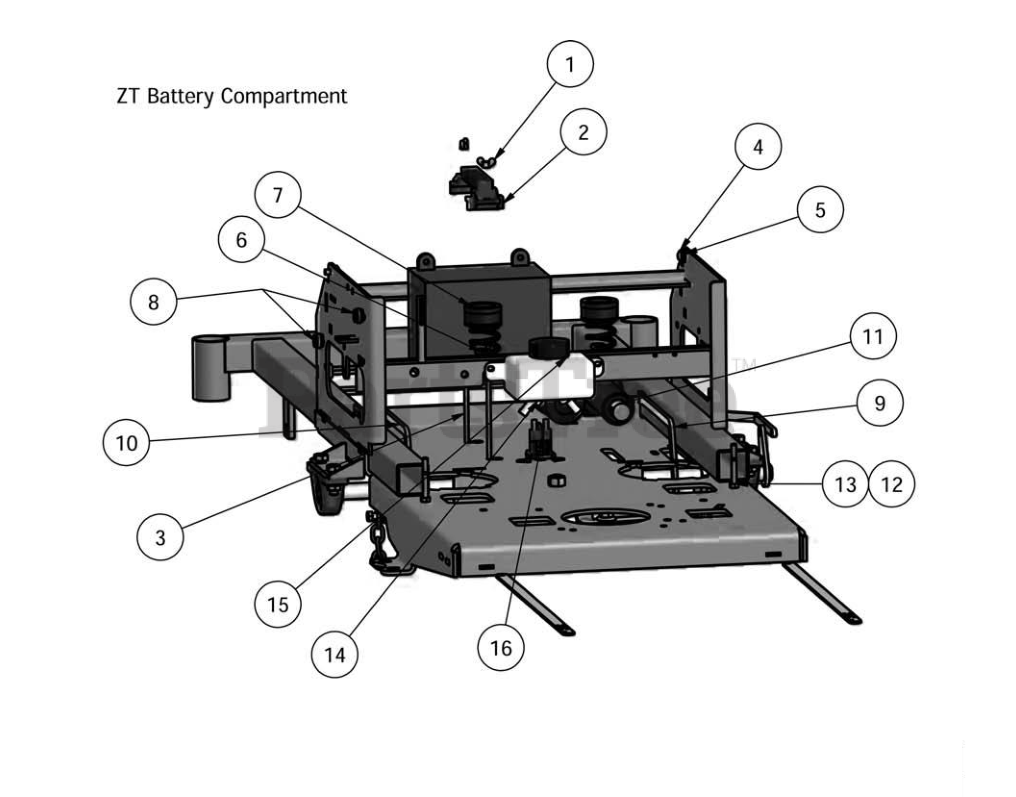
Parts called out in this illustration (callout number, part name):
1	1/4" Wing Nut
2	Battery Holder
3	Stove Bolt
4	5/16" x 3/4" Carriage bolt
5	.360 ID Plastic Washer
6	Seat Spring
7	Seat Bumper
8	1/2" Tank Spacer
9	Transaxle Drive Rod (Right)
10	Transaxle Drive Rod (Left)
10A	Quick Release Ball Joint
11	Actuator ZT
12	5/16" x 3" Hex Bolt
14	ZT Hydraulic Tank
15	ZT Hydraulic Tank Cap
16	ZT Solenoid
